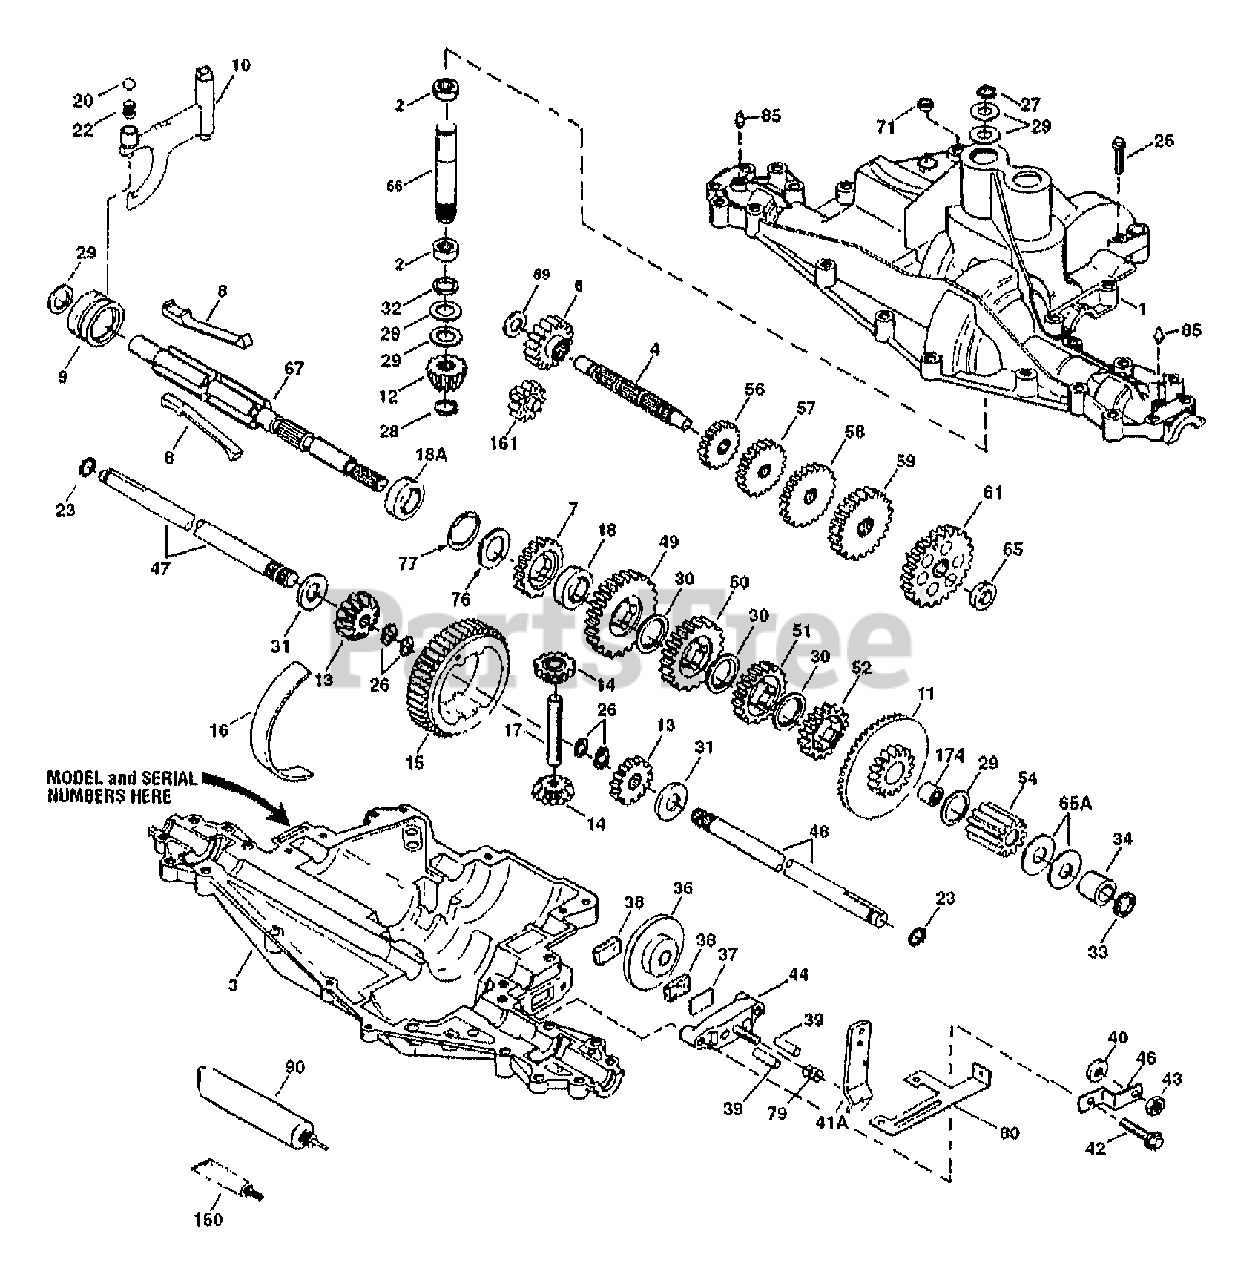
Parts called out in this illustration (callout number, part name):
1	TRANSAXLE COVER
2	NEEDLE BEARING
3	TRANSAXLE CASE
4	COUNTERSHAFT
6	SPUR GEAR (16 TEETH)
7	SPUR GEAR (22 TEETH)
8	SHIFT KEY
9	SHIFT COLLAR
10	SHIFT ROD & FORK
11	BEVEL GEAR & BEARING (INCL. 174)
12	BEVEL PINION (14 TEETH)
13	BEVEL GEAR (16 TEETH)
14	DIFFERENTIAL PINION
15	RING GEAR
16	BEARING STRIP
17	DRIVE PIN
18	NEUTRAL SPACER
18A	NEUTRAL SPACER
20	BALL, 5/16" DIA.
22	SPRING
23	SEAL RING
25	SCREW, 1/4-20X1-1/4"
26	RETAINING RING
27	RETAINING RING
28	RETAINING RING
29	WASHER
30	WASHER
32	"O" RING
33	"O" RING
36	BRAKE DISK
37	BRAKE PAD PLATE
38	BRAKE PAD (PKG. OF 2)
39	DOWEL PIN
41	BRAKE LEVER
42	SCREW, 1/4-20X1-1/4"
43	LOCKNUT, 5/16-24
44	BRAKE PAD HOLDER
46	BRAKE LEVER BRACKET
47	AXLE (16-1/4" LONG)
48	AXLE (11" LONG)
49	SPUR GEAR (30 TEETH)
50	SPUR GEAR (25 TEETH)
51	SPUR GEAR (22 TEETH)
52	SPUR GEAR (19 TEETH)
54	SPUR GEAR (11 TEETH)
56	SPUR GEAR (20 TEETH)
57	SPUR GEAR (25 TEETH)
58	SPUR GEAR (28 TEETH)
59	SPUR GEAR (30 TEETH)
61	SPUR GEAR (34 TEETH)
66	INPUT SHAFT
67	SHIFTER & BRAKE SHAFT
71	SQUARE CUT RING
77	INVERTED RETAINING RING (PKG. OF 2)
80	BRAKE BRACKET
85	LUBRICATION FITTING
90	GREASE (32 OZ. BOTTLE BENTONITE GREASE)
150	GASKET ELIMINATOR (LOCTITE #515)
161	REVERSE IDLER
174	NEEDLE BEARING
